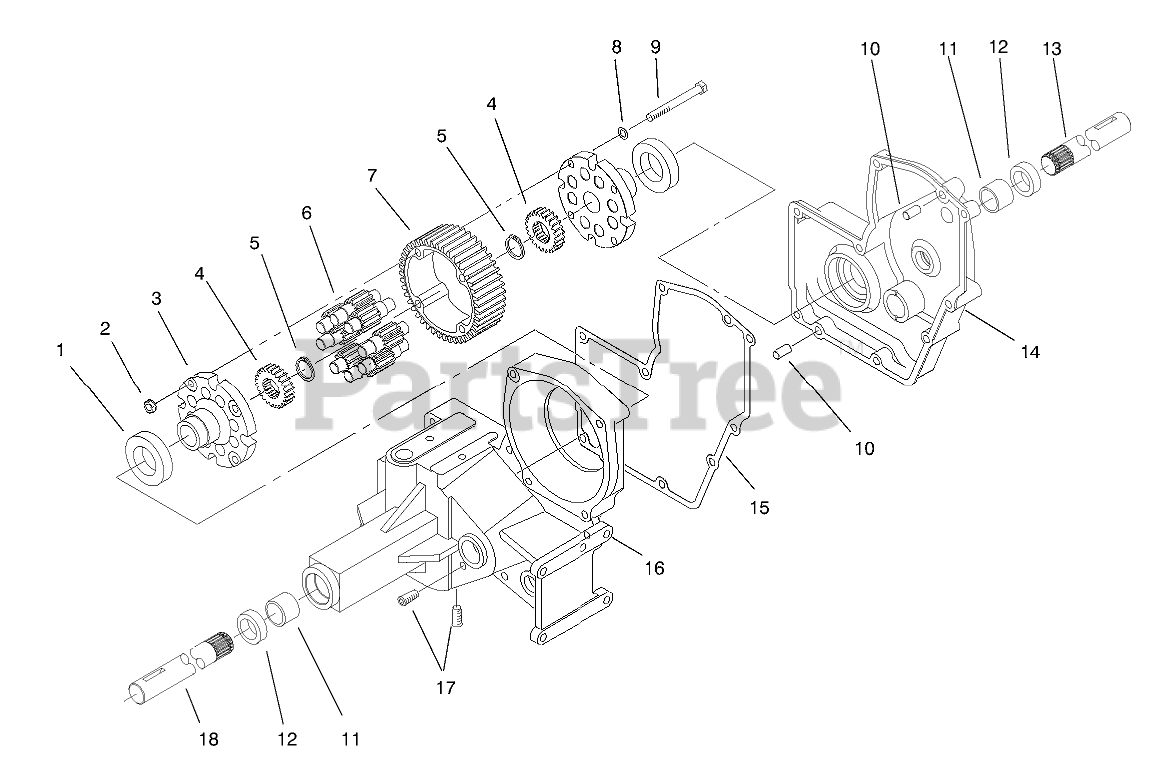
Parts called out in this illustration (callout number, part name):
1	BEARING-BALL
3	END CAP-DIFFERENTIAL
4	GEAR-AXLE DIFFERENTIAL
5	RING-SNAP
6	GEAR-PINION, 11T
7	GEAR-DIFFERENTIAL RING, 43T
8	WASHER
9	BOLT-HEX
10	PIN-LOCATING
11	BEARING
12	SEAL-OIL
13	AXLE-REAR LH
14	Case-Transaxle
15	GASKET-TRANSMISSION
16	Case-Transaxle
16	CASE-TRANSMISSION RH
16:1	Case-Transaxle
16:2	DECAL - DANGER
18	AXLE-REAR RH
